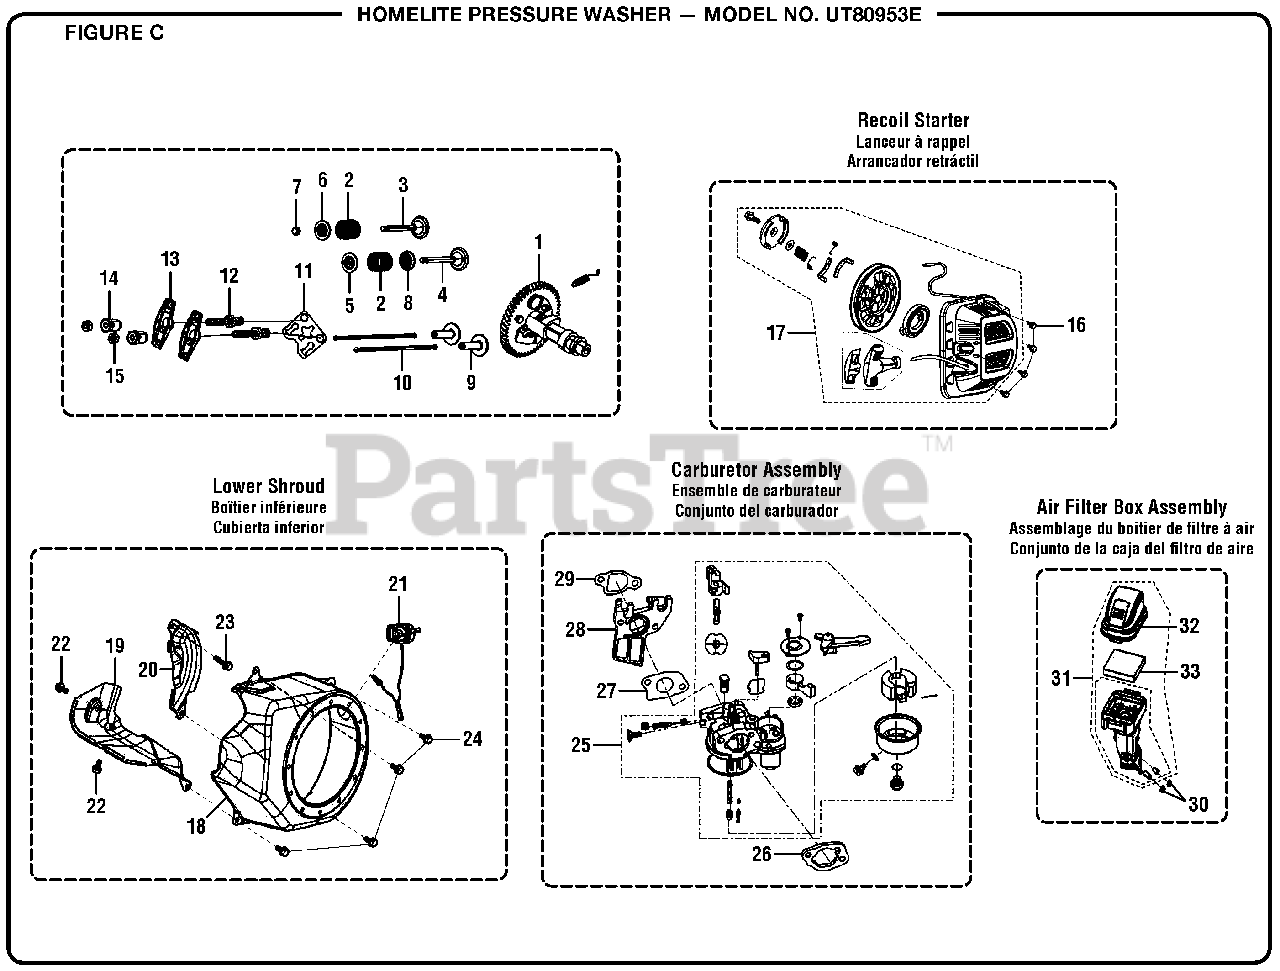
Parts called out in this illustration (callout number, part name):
1	Camshaft Assembly
5	Valve Spring Seat
6	Exhaust Valve Retainer
11	Stop Plate Assembly
12	Valve Adjusting Bolt
14	Valve Adjusting Nut
17	Recoil Starter Assembly
18	Shroud
19	Cylinder Body Shroud
21	Stop Engine Switch Assembly
25	Carburetor Assembly
26	Air Cleaner Gasket
27	Carburetor Gasket
28	Carburetor Insulator Plate
29	Carburetor Insulator Gasket
32	Air Cleaner Cover
33	Air Cleaner Element
